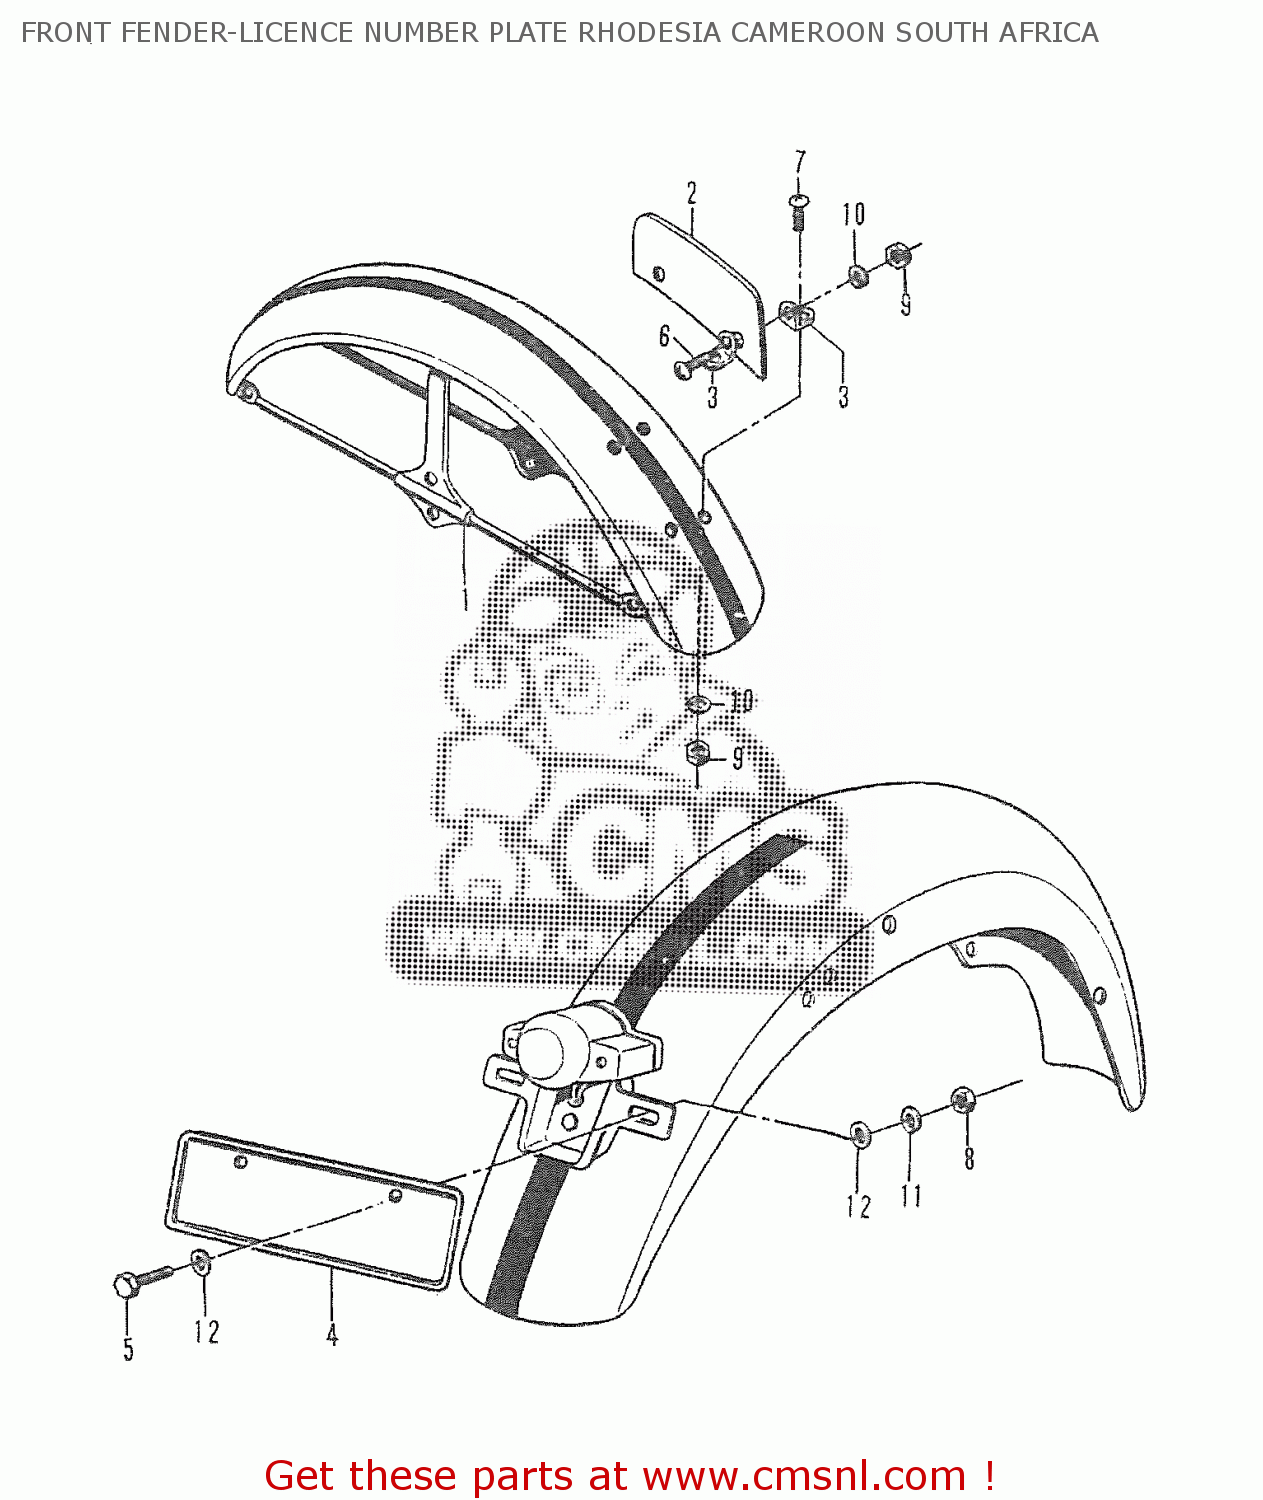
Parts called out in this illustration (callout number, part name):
1	FRONT FENDER
2	PLATE, FRONT LICENCE
3	PLATE, LICENCE FITTING
4	PLATE,RR LICENSE
5	HEXAGON BOLT
6	CROSS HEAD SCREW
7	CROSS HEAD SCREW
8	HEXAGON NUT
9	HEXAGON NUT
10	LOCK WASHER
11	LOCK WASHER
12	FLAT WASHER
